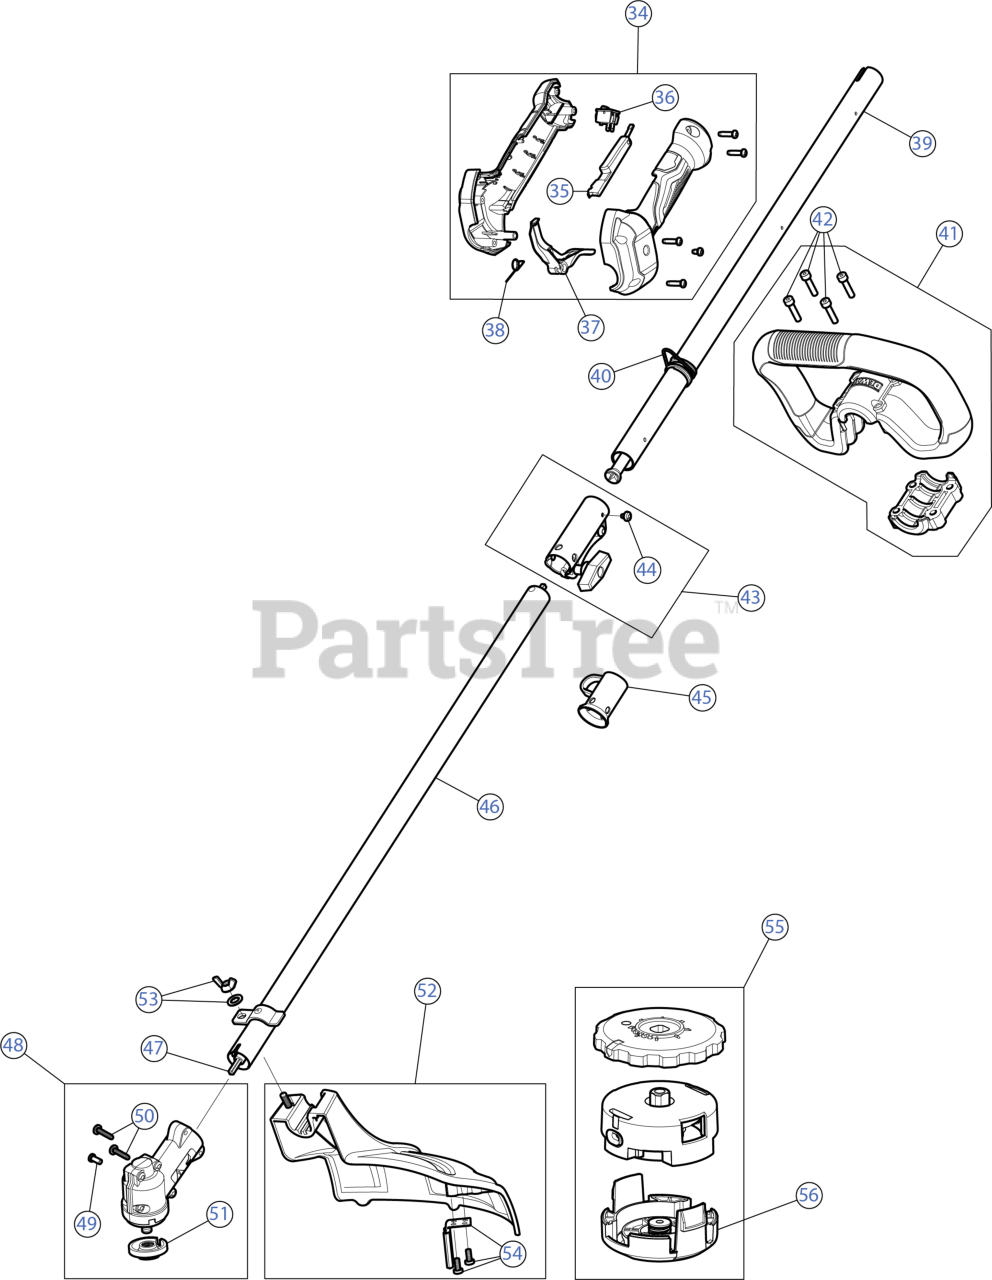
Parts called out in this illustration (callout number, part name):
34	THROTTLE GRIP
35	THROTTLE LOCK LEVER
36	SW, MOMENTARY ON/O
37	THROTTLE TRIGGER
38	TRIGGER SPRING
39	UPPER DRIVE SHAFT
40	CLAMP-SHOULDER STR
41	HANDLE
42	HANDLE BOLT
43	CLICK LINK
44	SCREW, 10-32X.250 TA
45	HANGER
46	LOWER SHAFT HOUSING
47	LOWER DRIVE SHAFT
48	GEARBOX LCBC
49	SCREW, 8-32 x .312 P
50	SCREW #10-24X11/16 T-25
51	CUTTING HEAD SPACER
52	GUARD
53	BLADE GUARD MOUNTING HARDWARE
54	BLADE ASSEMBLY W/HDW
55	HEAD ASM SS QUIKLD.095
56	CAP SNAP SML:DEWALT
